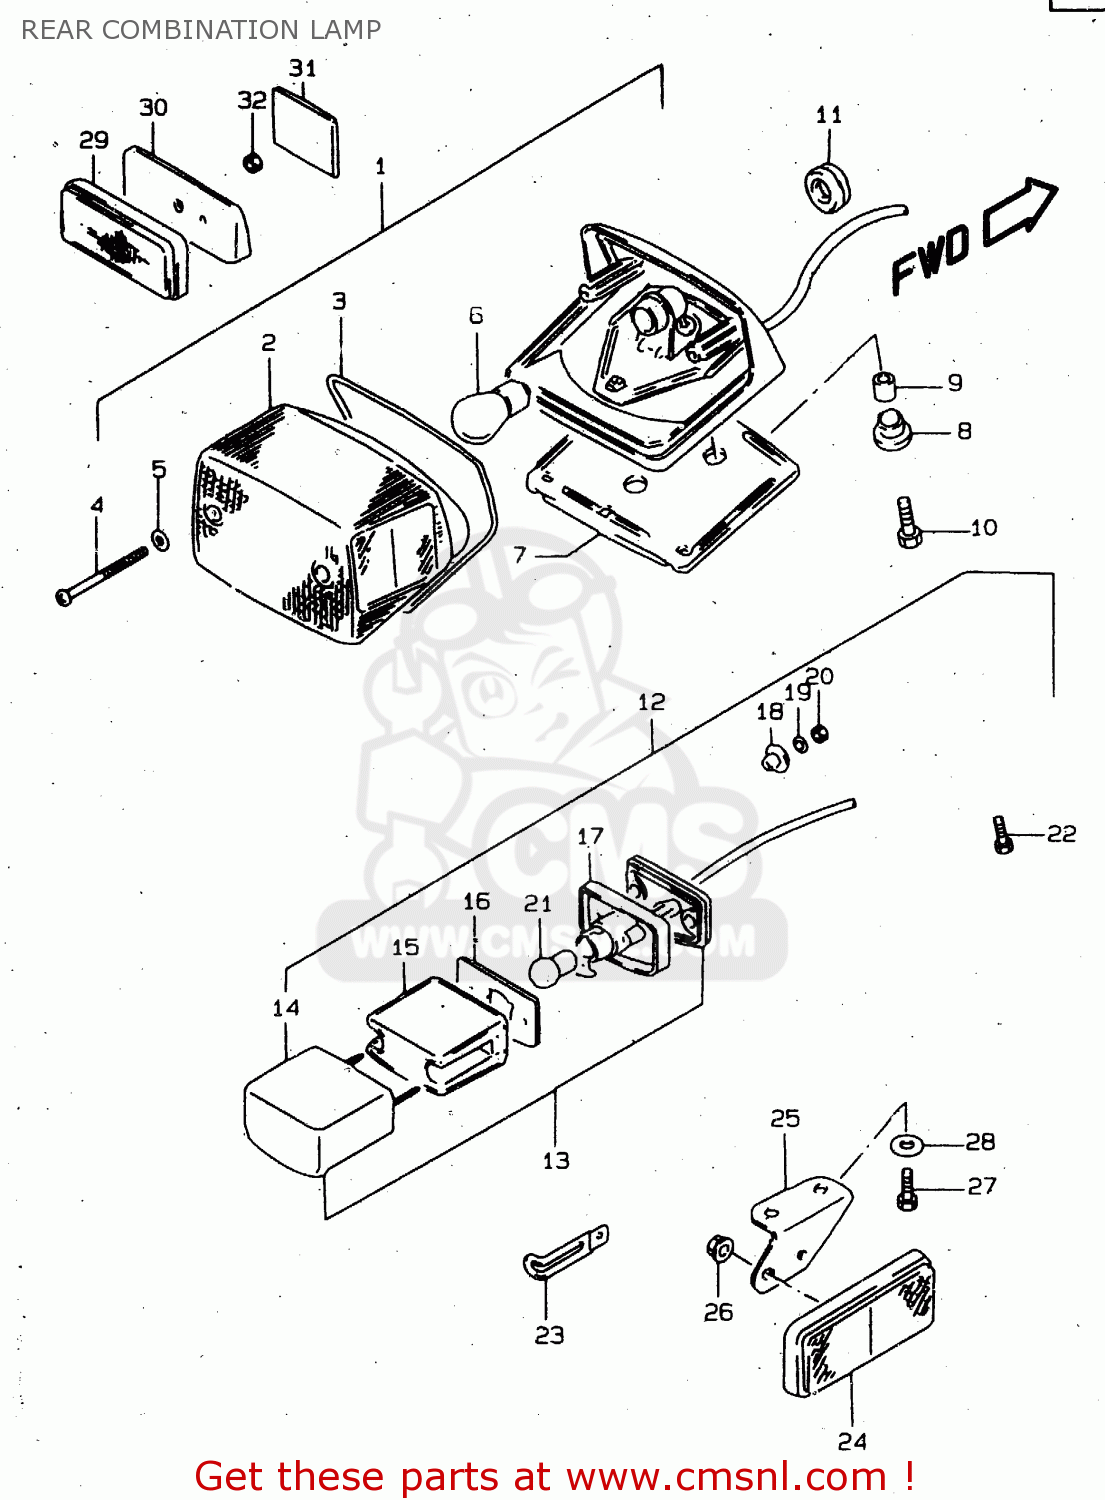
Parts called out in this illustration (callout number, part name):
1	LAMP ASSY,RR COMBINATION
2	LENS
3	GASKET (NAS)
4	SCREW
5	GASKET (NAS)
6	BULB(12V21/5W)
7	CUSHION
8	CUSHION
9	SPACER
10	BOLT(6X25)
11	GROMMET
12	LAMP ASSY,LICENSE
13	LAMP ASSY,LICENSE
14	COVER
15	LENS
16	GASKET,LICENSE LAMP (NAS)
17	HOUSING,LICENSE LAMP
18	SPACER
19	WASHER,LOCK
20	NUT
21	BULB(12V5W,BF150-40160A)
22	BOLT(6X20)
23	CLAMP(L:65)
24	REFLEX REFLECTOR,FR SIDE
25	BRACKET,RR SIDE RR,L
26	NUT
27	SCREW
28	WASHER
29	REFLECTOR ASSY,RR
30	SPACER,RR REFLECTOR
31	TAPE,TOOL BAG PROTECTOR
32	NUT
